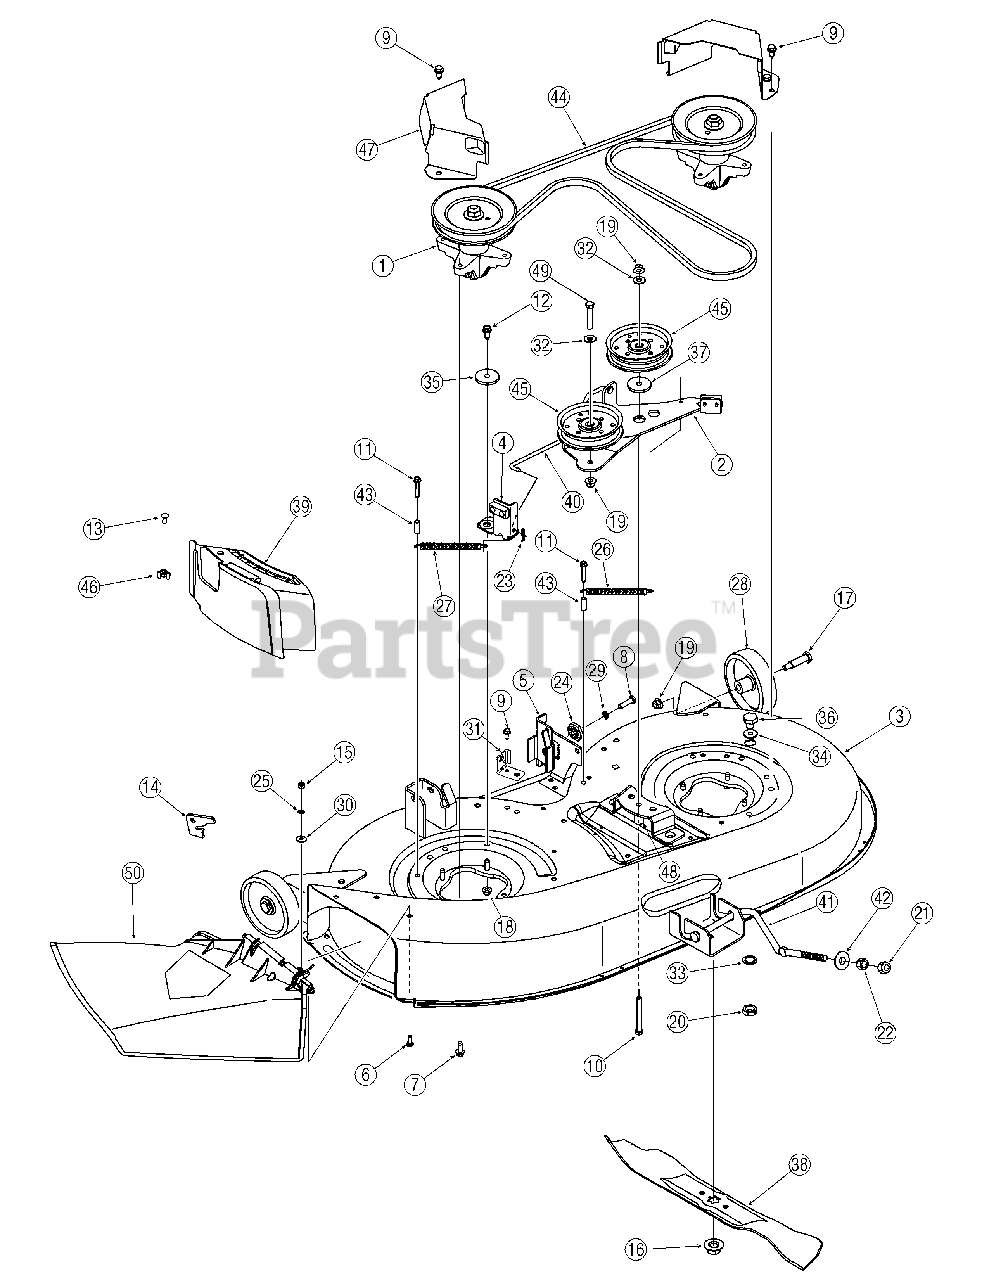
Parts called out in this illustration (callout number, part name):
1	Spindle Assembly, Pul, 6.23"
3	Deck Shell, 42" (w/o Wheel Bracket)
6	Screw, 1/4-20, .75, Gr5
7	Screw, 5/16-18, 0.875
8	Screw, 5/16-18, 1.250
9	Screw, 5/16-12, 0.750
10	Screw, 3/8-16, 3.50, Gr5
11	Screw, 1/4-20, 1.500
12	Screw, 5/16-18, .75, Gr5
13	Carriage Screw, , 1/4-20 x .62 (if equipped)
14	Chute Stop
15	Nut, Hex, 1/4-20, Gr5
16	Nut, Flange, 5/8-18
17	Screw, Shldr, .498 x 1.53, 3/8-16
18	Nut, Flange Lock, 5/16-18, GrF
19	Nut, Flange Lock, 3/8-16, GrF
20	Nut, Hex, M16-1.5
21	Nut, Hex Lock, 1/2-13, Gr8
22	Nut, Hex, 1/2-13, Gr5
23	Pin, Cot, .072 Dia. x 1.13 LG
24	Gear, Deck Adjustment
25	Nut, Push, .25 ID x .50 OD
26	Spring, Exten. , .75 Dia. X 6.375
27	Spring, Exten. , .50 Dia. X 6.375
28	Wheel, Deck 5.0 x 1.38 (if equipped)
29	Washer, Lock, 5/16
30	Washer, Bell, .265 x.75 x .062
32	Washer, Flat, .385 x .87 x .06
33	Washer, Lock, 5/8, Internal
34	Washer, Flat, .64 x 1.24 x .06
35	Spacer, Shoulder, .5000 x .1475
36	Plug, Screw, M16 x 1.5
37	Spacer, Shoulder, .8840 x .190
38	Blade, 21.23", Star 3-in-1
39	Mulch Plug (if equipped)
40	Control Rod, Brake
41	Deck Rod, Front Adjustable
42	Pivot Cup, Deck Lift
43	Spacer, .260 x .372 x 1.030
44	Belt, V-Type
45	Idler Pulley, 4.25" Dia.
46	Wing Nut, 1/4-20 (if equipped)
48	Spacr, 3/8 ID x .68 OD x 1.46 Lg
49	Screw, 3/8-16 x 1.75
50	Chute Assembly, Discharge
